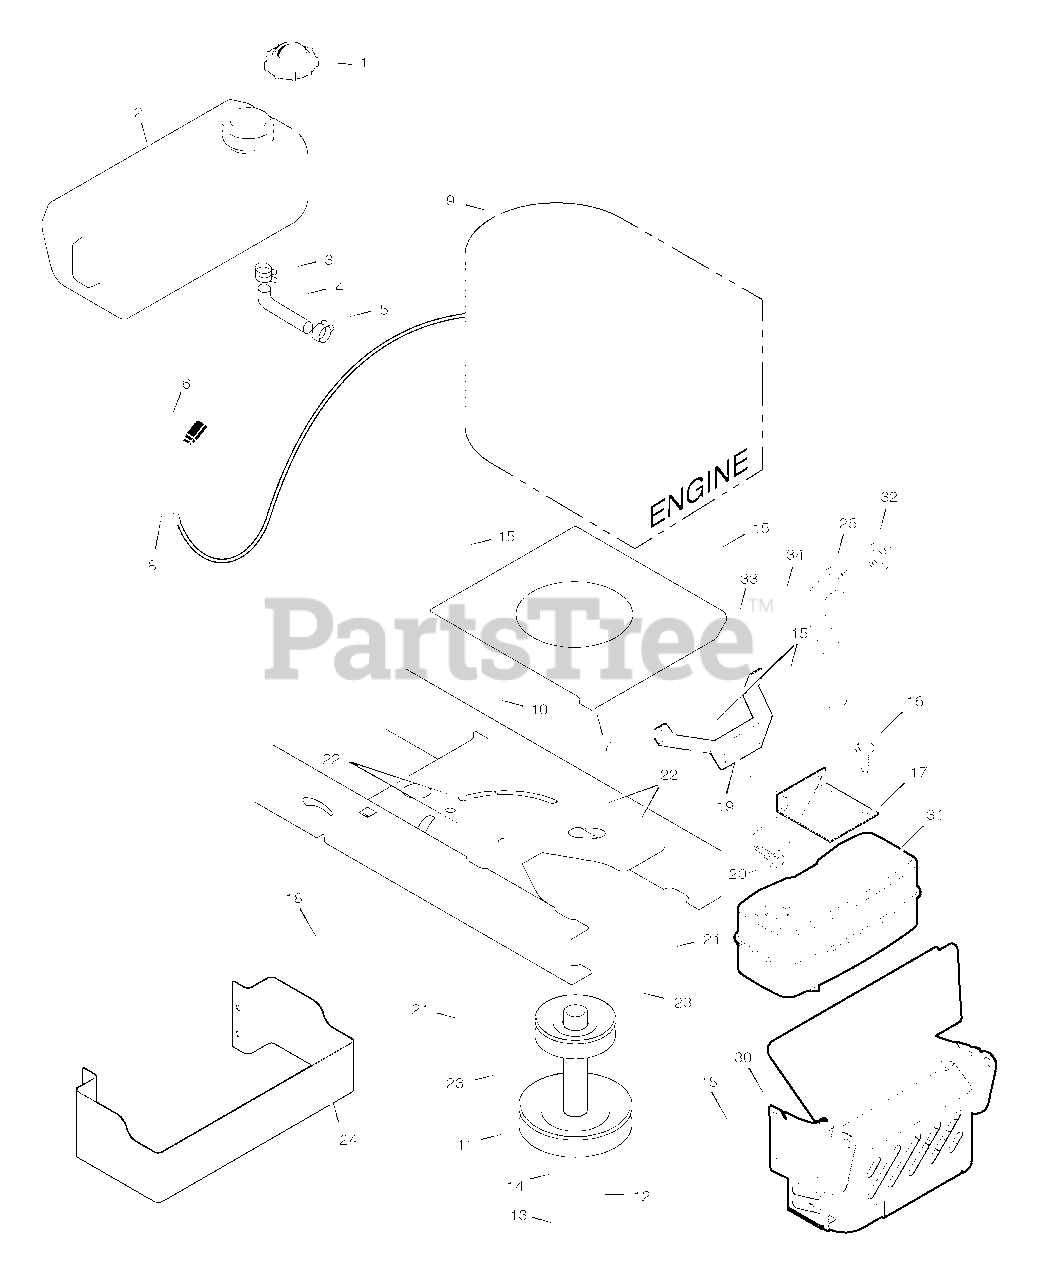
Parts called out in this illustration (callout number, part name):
1	Fuel Cap
2	Fuel Tank
3	Hose Clamp
4	Fuel Line (Must cut to length)
5	Hose Clamp
7	Plate, Engine
8	Throttle Control
9	Engine, Briggs & Stratton *
10	Bolt, Engine Mount
11	Stack Pulley Assembly
12	Lockwasher
13	Bolt, Hex
17	Bracket, Muffler
19	Bracket, Muffler Mount
21	Guide, Belt
22	Nut, Flange
23	Guide, Belt
24	GUARD, Heat Shield
25	Exhaust Tube, Single
30	Shield, Heat
31	Muffler
32	GASKET, Exhaust
34	Washer
